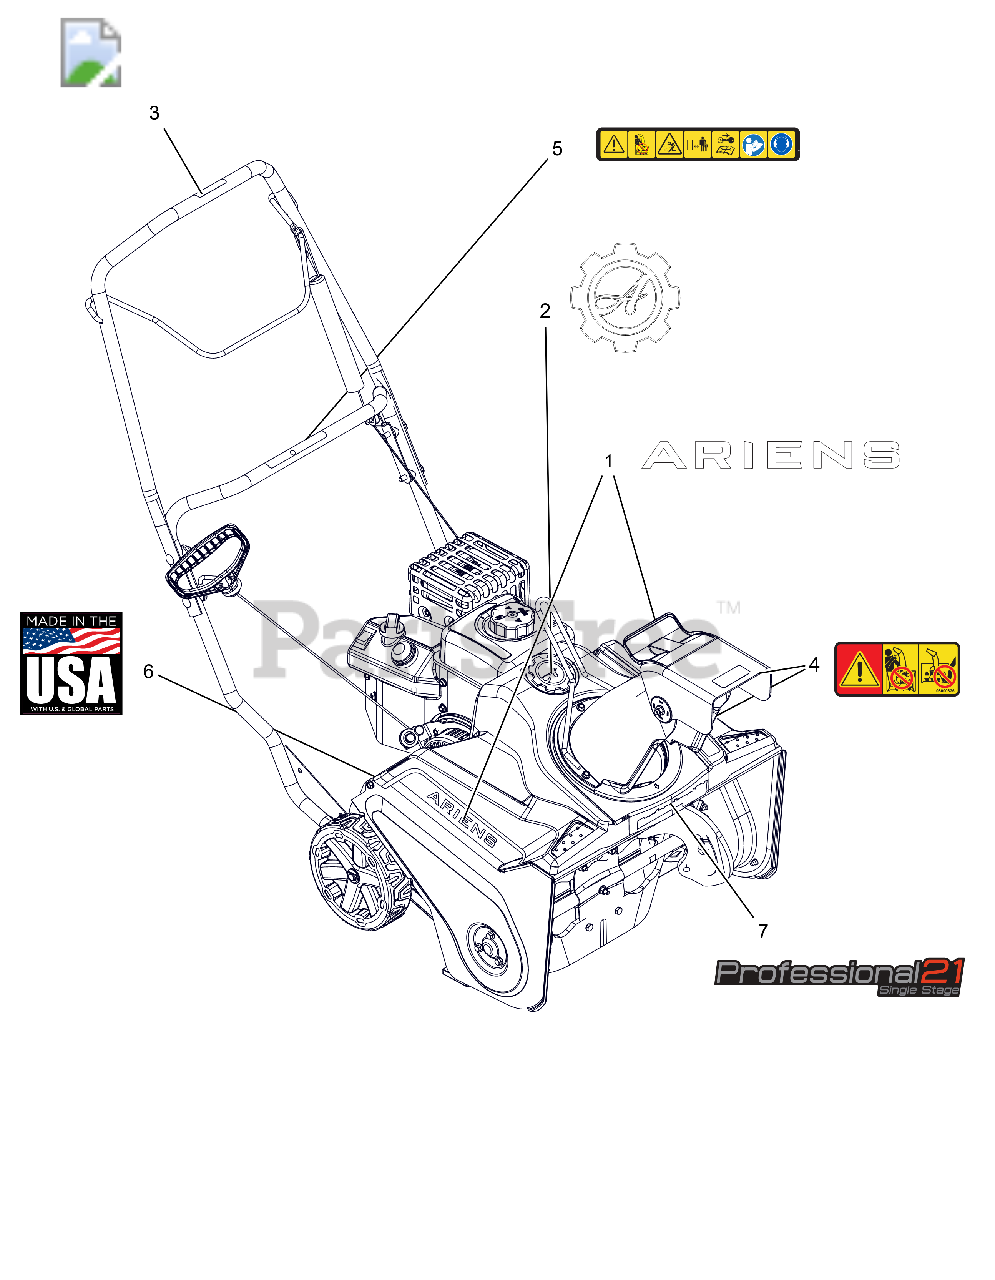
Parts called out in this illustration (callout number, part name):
1	DECAL, ARIENS (6.50")
2	DECAL, ARIENS-GEAR BADGE -THK
3	DECAL-AUGER/IMPELLER BAIL
4	DECAL, DANGER SINGLE STAGE
5	DECAL,DASH - SAFETY
6	DECAL, MADE IN USA
7	DECAL,COVER - PRO 21" CSS
